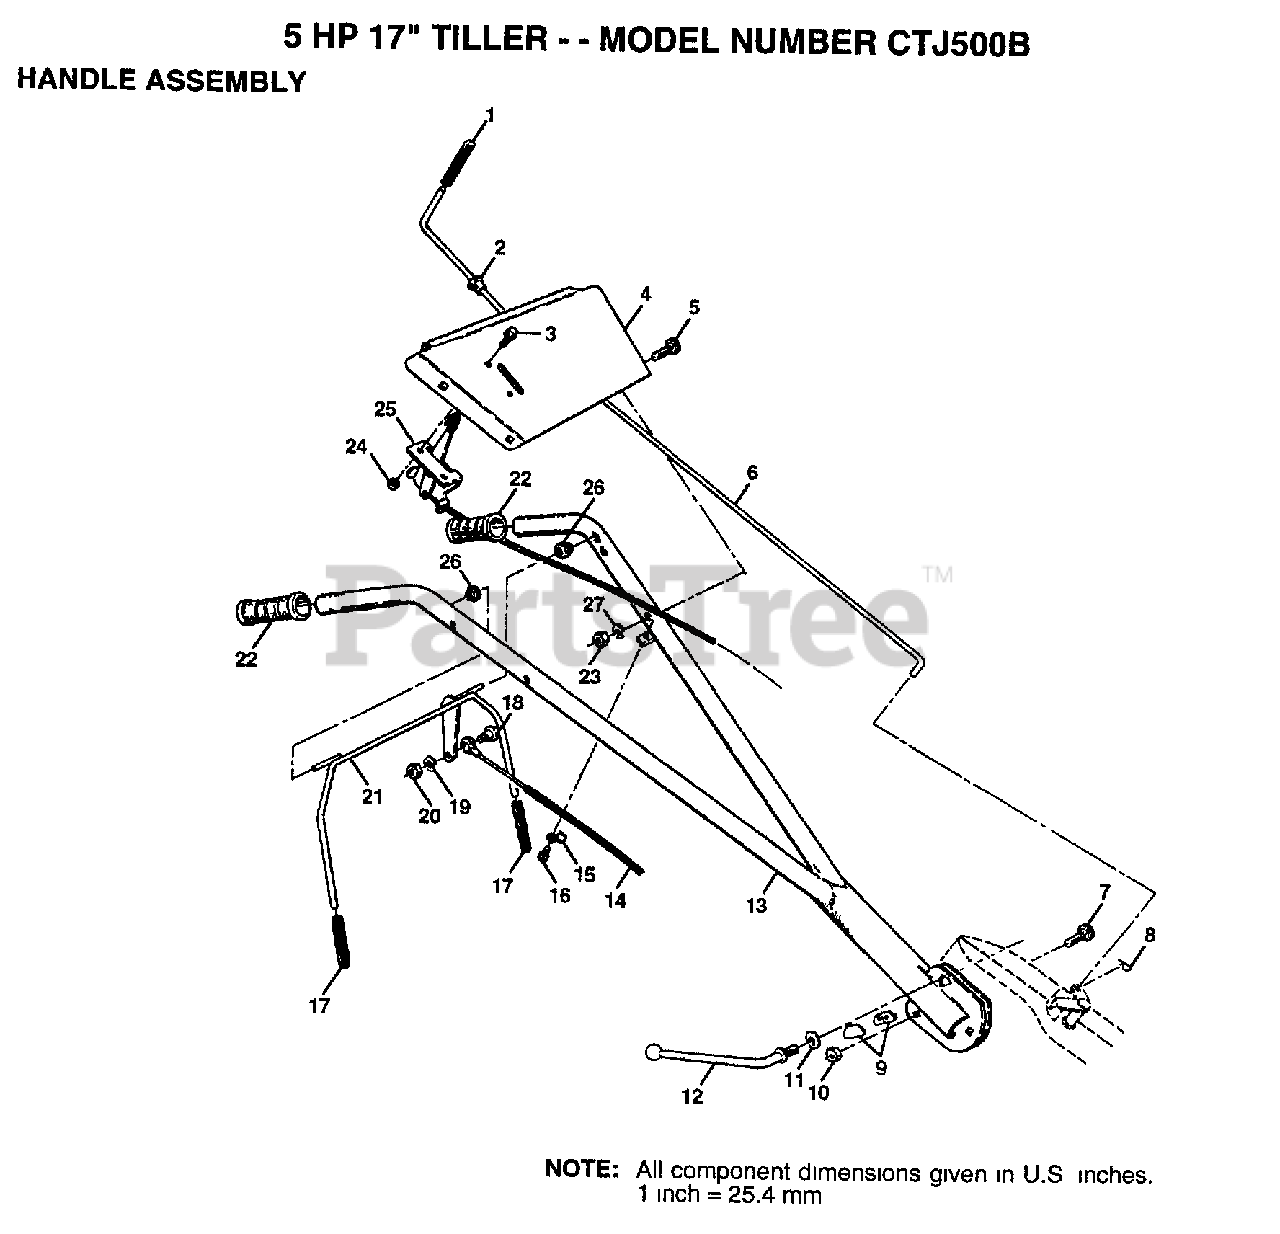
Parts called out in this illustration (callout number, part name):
1	GRIP TI
2	BUSHING
3	SCREW
5	BOLT CARRIAGE CRT
6	ROD SHIFT CRT
7	BOLT D
8	RETAINER M
9	LOCK CRT
10	LOCKNUT
11	WASHER CRT
12	LEVER LOCK CRT
14	CABLE.CLUTCH.CRT
15	CONDIUT CLIP T
17	GRIP BAR CRT
18	SHOULDER BOLT ST
19	LOCKWASHER
21	HANDLE BAR CRT
22	GRIP HDLE NUBBED
23	NUT
25	"CONT,THROTTLE"
27	LOCKWASHER
